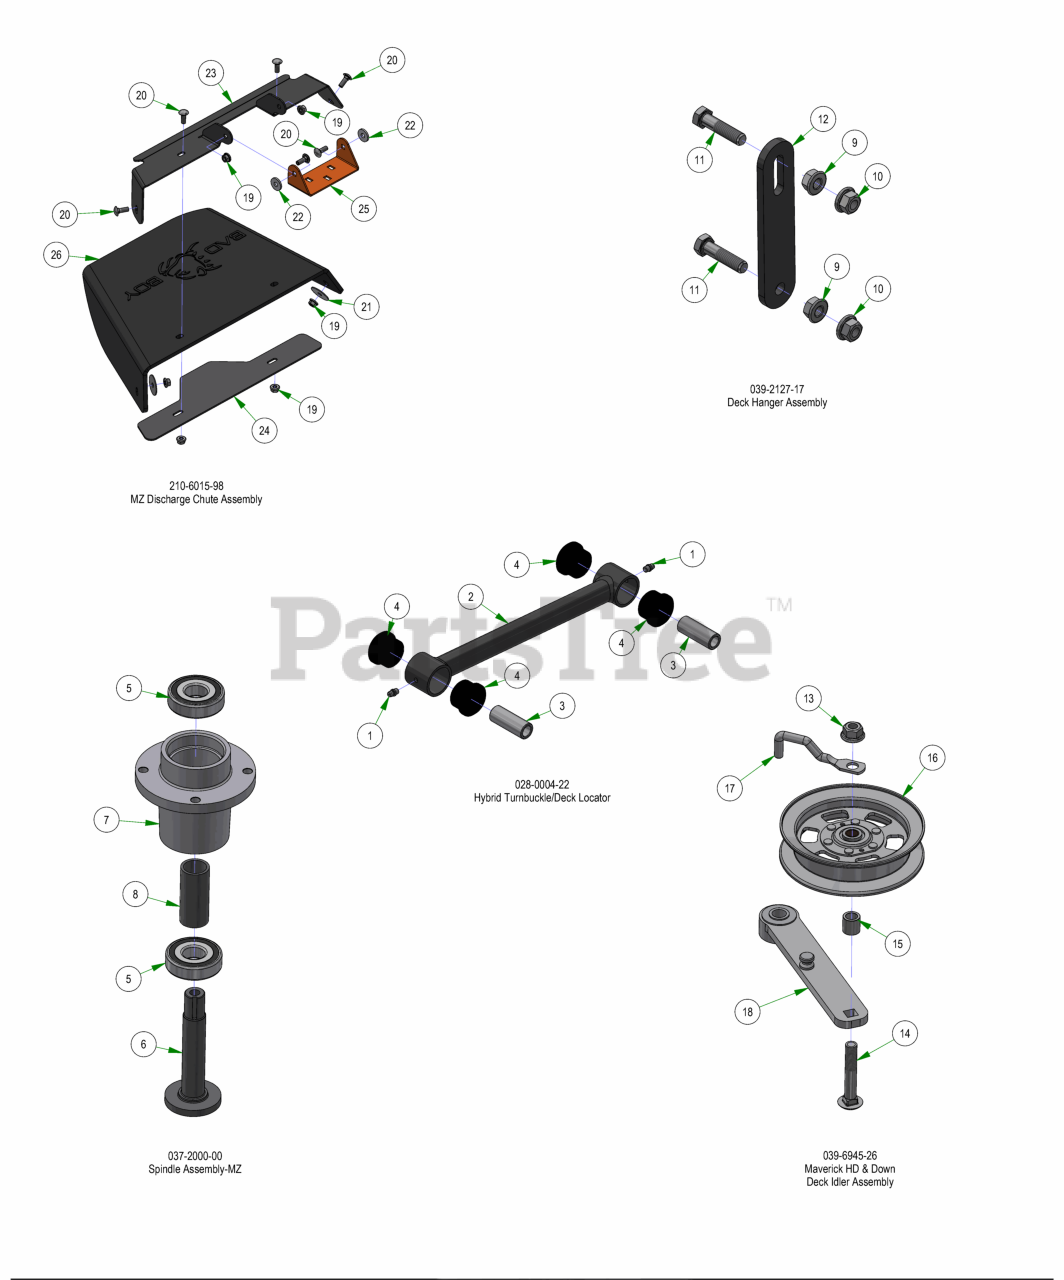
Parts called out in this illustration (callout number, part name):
1	1/4-28 Grease Fitting
2	2022 Isolator Turnbuckle Body
3	2018 Maverick Bushing Sleeve
4	2018 Maverick Bushing
5	Spindle Bearing
6	Spindle Shaft
7	Spindle Housing
8	Spindle Spacer-Component
9	3/8-16 HEX SERRATED FLANGE NUT HARD/ZINC
10	3/8-16 NYLON INSERT FLANGE LOCKNUT (GR.F) ZINC
11	3/8-16 X 1-1/2 HEX CAP SCREW (GR.5) ZINC
12	2017 MZ/ZT Deck Hanger
13	1/2-13 NYLON INSERT FLANGE LOCKNUT ZINC
14	1/2-13 x 3 Carriage Bolt Grade 5
15	.51 ID X .75 OD X .75 LGTH SOLID SPACER ZINC
16	5" Idler Pully
17	2025 R-Series Belt Retainer
18	2025 Tensioner Arm With Bearings
19	5/16-18 NYLON INSERT FLANGE LOCKNUT ZINC
20	5/16-18 X 7/8 CARRIAGE BOLT ZINC
21	5/16 FENDER WASHER (1-1/2 OD) ZINC
22	.360 ID X .983 OD X .120 THICK FLAT WASHER NYLON
23	Discharge Chute Bracket 48 MZ (Upper)
24	2017 MZ Discharge Chute Bracket-Lower
25	Chute Hanger 48 MZ
26	Rubber Discharge Chute MZ (Component)
